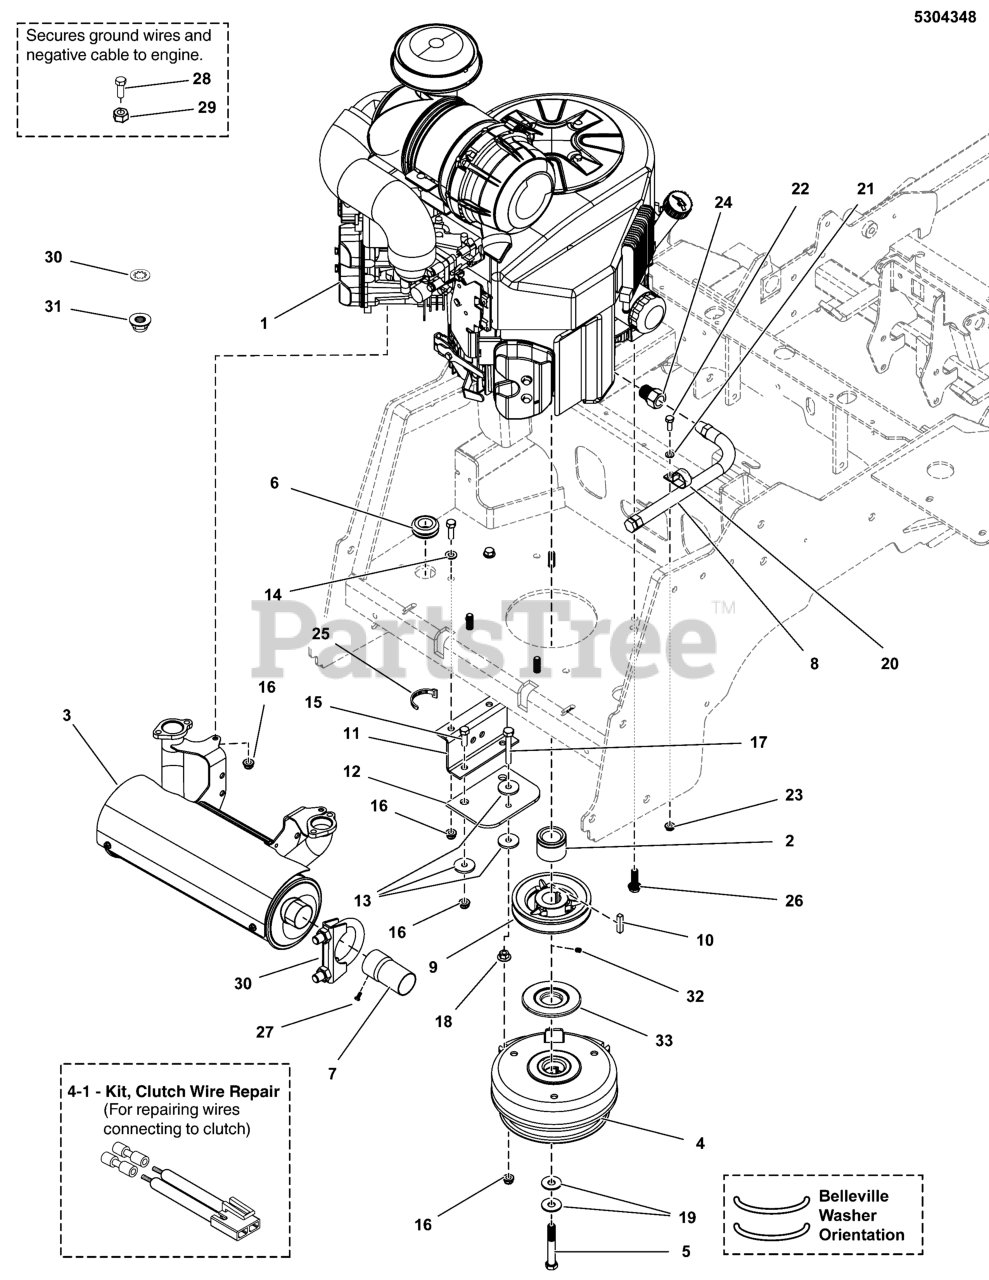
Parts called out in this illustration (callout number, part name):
2	SPACER, 1.13 X 1.75 X 1.35, CZ
3	MUFFLER 35-37HP KAWASAKI 5 CAN
4	CLUTCH, 250 FT-LBS, WATER GUARD
4-1	KIT, CLUTCH WIRE REPAIR
5	BOLT, CRANKSHAFT, 7/16-20 X 3-1/4, GD 8
6	GROMMET, 7/8"ID, 1/4" THICK STK
7	EXTENSION, TAILPIPE, 3" - BLACK
8	HOSE-OIL DRAIN .375ID 16.5L
9	PULLEY, 4.75 OD X 1-1/8 BORE, BC-48
10	KEY, 1/4" SQ. X 1-1/4
11	ANCHOR, CLUTCH, IS600-IS700 - BLK
12	CLUTCH ANCHOR PAD
13	WASHER, .34 X 1.25 X 10 GA
14	WASHER, 5/16" SAE
15	BOLT, 5/16-18 X 1" GRD5 YZ
16	NUT, 5/16-18 HEX NYLOCK FLANGE NUT
17	BOLT, 5/16-18 X 2-1/4 TFL, GD5 YZ
18	NUT, 5/16-18 HEX SERRATED FLANGE (LARGE)
19	BELLEVILLE WASHER, 1.1875 X .442 X .098
20	CLAMP, VINYL INSULATED, 1.00
21	WASHER, 1/4 SAE
22	BOLT, 1/4"-20 X 3/4" GD5 YZ
23	NUT, 1/4-20 HEX SERR. FLANGE
24	ADAPTER, Oil Drain
25	TIE,SELF-LOCKING, 24"
26	BOLT, HEX FLG, SER, GD5 3/8-16 X 1-1/4" PACH CZ
27	SCREW, SELF-TAP, #8-32 X 3/8. WASH HEX, CZ
28	BOLT, M8-1.25 X 20 MM GD 8.8
29	NUT, HEX, M8-1.25, CZ, GD 8.8
30	WASHER, 5/16" Internal Tooth Lock
31	NUT, M8-1.25 Hex Serrated Flange
32	SET SCREW, 5/16-18 X 3/8, KNURL, W/PATCH
33	WATER GUARD, WARNER C 250 FT-LBS CLUTCH
